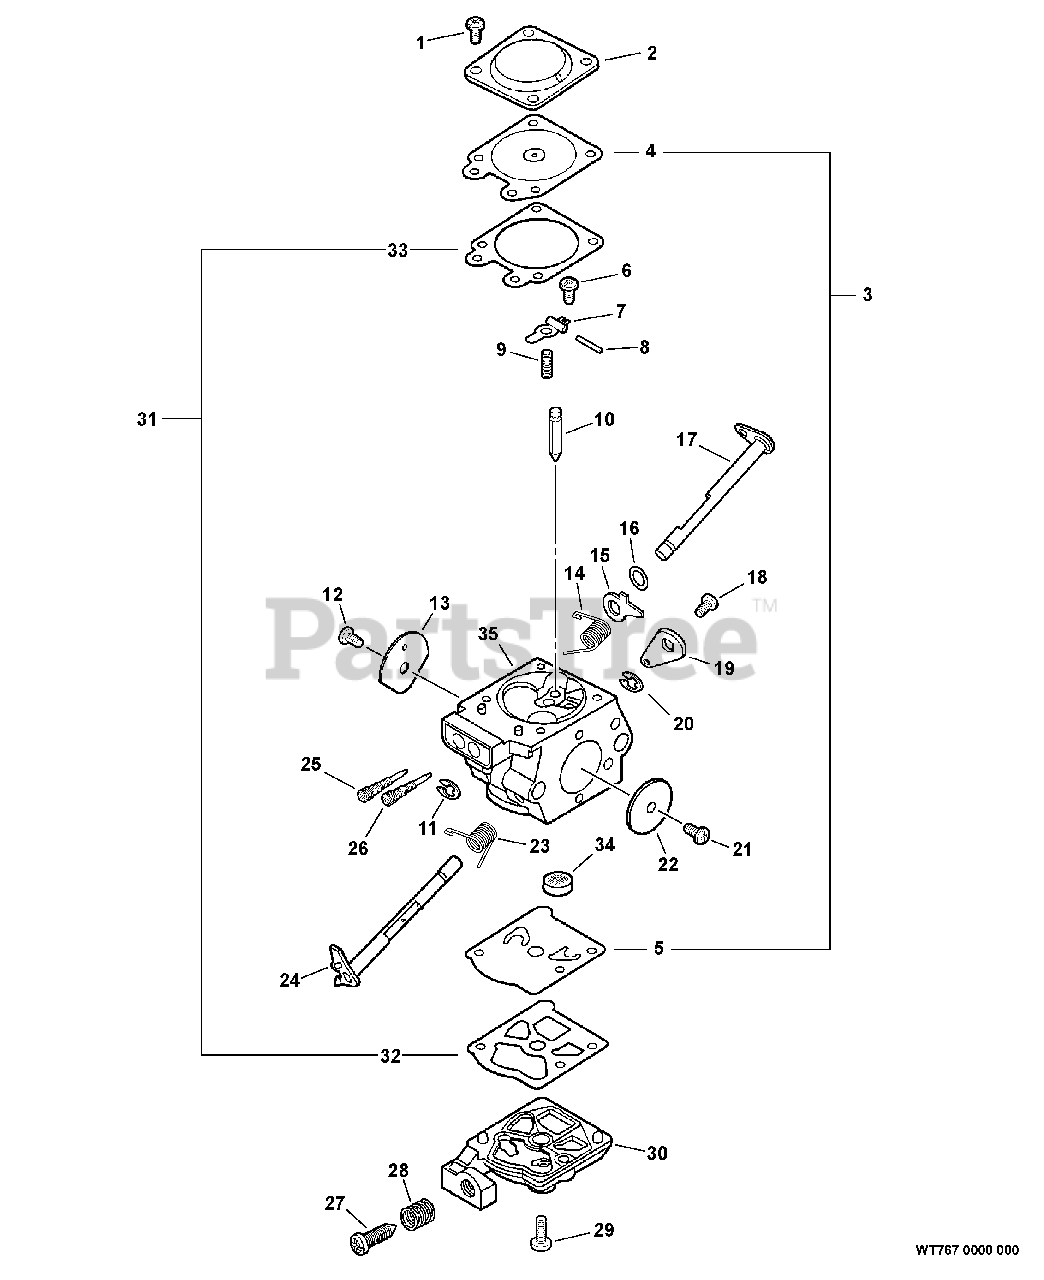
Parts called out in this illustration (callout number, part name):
1	SCREW
2	COVER, DIAPHRAGM
3	DIAPHRAGM KIT
4	DIAPHRAGM, METERING
5	DIAPHRAGM, PUMP
6	SCREW, METERING LEVER PIN
7	LEVER, METERING
8	PIN, METERING LEVER
9	SPRING, METERING LEVER
10	VALVE, INLET NEEDLE
11	RING, RETAINING
12	SCREW
13	VALVE, CHOKE
14	ROD, CHOKE
15	LEVER, FAST IDLE
16	WASHER
17	SHAFT, CHOKE
18	SCREW
19	LEVER, THROTTLE
20	RING, RETAINING
21	SCREW
22	VALVE, THROTTLE
23	SPRING, THROTTLE RETURN
24	SHAFT, THROTTLE
25	NEEDLE - HIGH SPEED
26	NEEDLE - LOW SPEED
27	SCREW, IDLE ADJUST
28	SPRING
29	SCREW, PUMP COVER
30	PUMP COVER ASSY
31	GASKET KIT
32	GASKET, PUMP
33	GASKET, METERING
34	STRAINER
35	BODY, CARBURETOR
